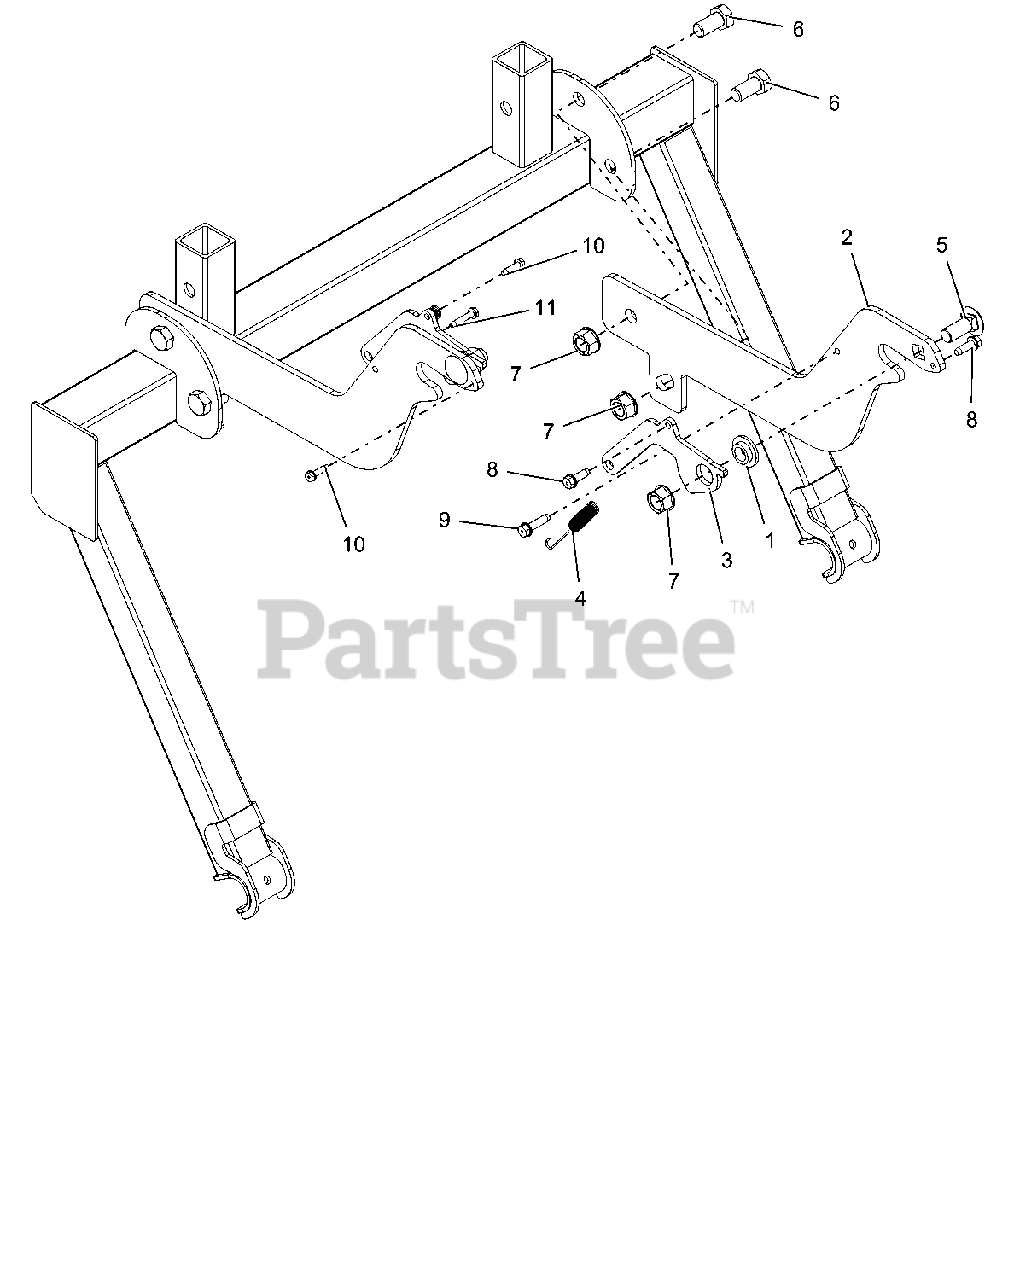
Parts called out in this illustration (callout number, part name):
1	BSHG, FLANGE .515X.750X.31X1.12
2	LATCH, ARM (BLACK)
3	BAGGER, LATCH (BLACK)
4	SPRG, EXTENSION
5	BLT-RDHDSQNK .50-13X1.25 G5 Y
6	BLT-HEX .50-13X1.00 GR5 YWZC
7	NUT, LK-TOP-FLG .50-13 YWZC
8	SCR-TAP .25-20X.75 HWH TR YWZ
9	SCR-TAP .25-20X1.00 HWH TR YZ
10	SCR-TAP 10-24X.75 HWH TR YWZC
11	SCR-TAP 10-24X1.00 HWH TR YWZC
